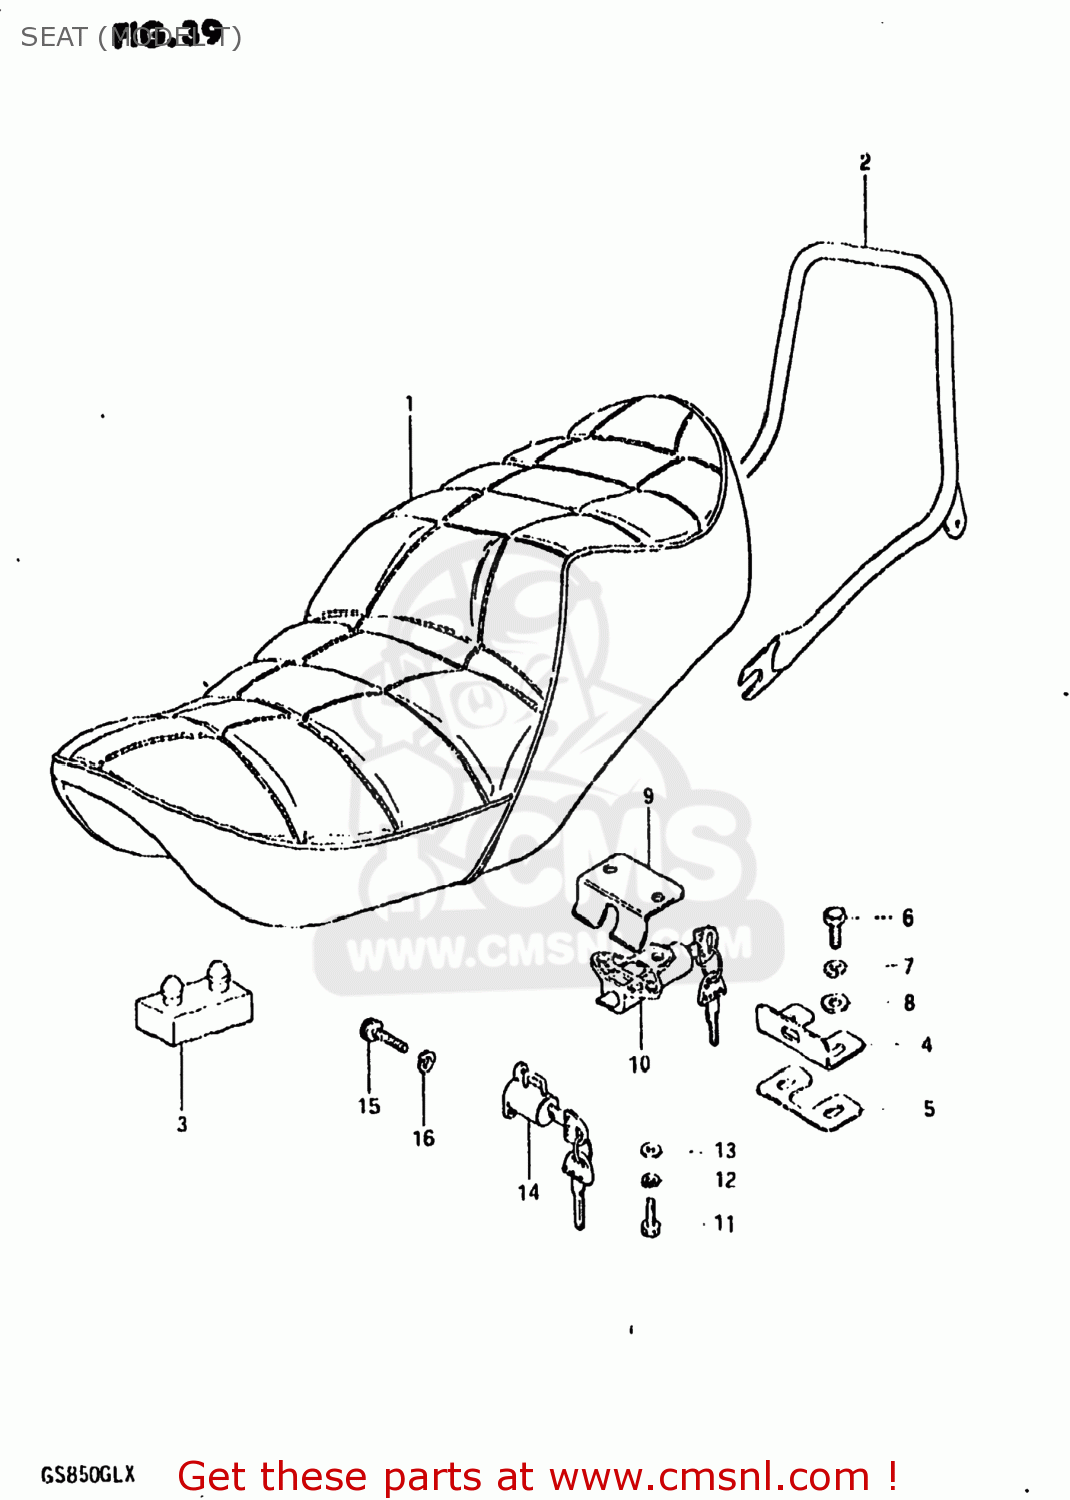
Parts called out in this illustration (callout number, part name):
1	SEAT ASSEMBLY
2	HANDLE,PILLION RIDER
3	CUSHION
4	STRIKER,SEAT LOCK
5	SHIM,SEAT LOCK STRIKER
6	BOLT, UPPER
7	LOCK WASHER
8	WASHER
9	PLATE,SEAT LOCK
10	LOCK ASSEMBLY,SEAT
11	BOLT
12	LOCK WASHER
13	WASHER 6MM
14	LOCK ASSEMBLY,HELMET
15	BOLT
16	LOCK WASHER
